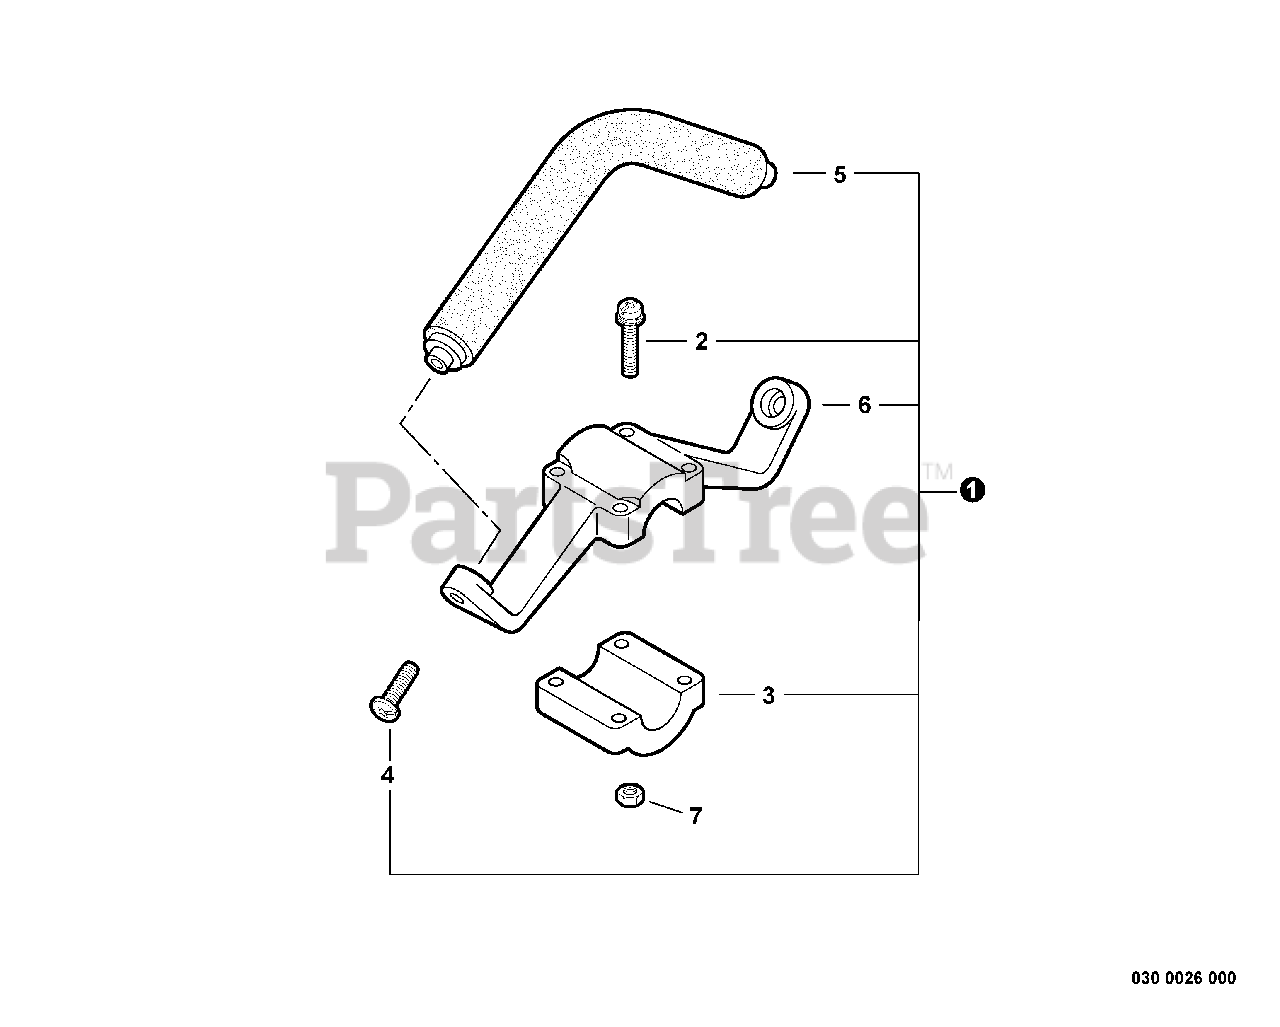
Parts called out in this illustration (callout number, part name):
1	FRONT HANDLE ASSY
2	SCREW 5×35
3	BRACKET, HANDLE - LOWER
4	SCREW 5×14
5	HANDLE, FRONT
6	BRACKET, HANDLE
7	NUT M5
